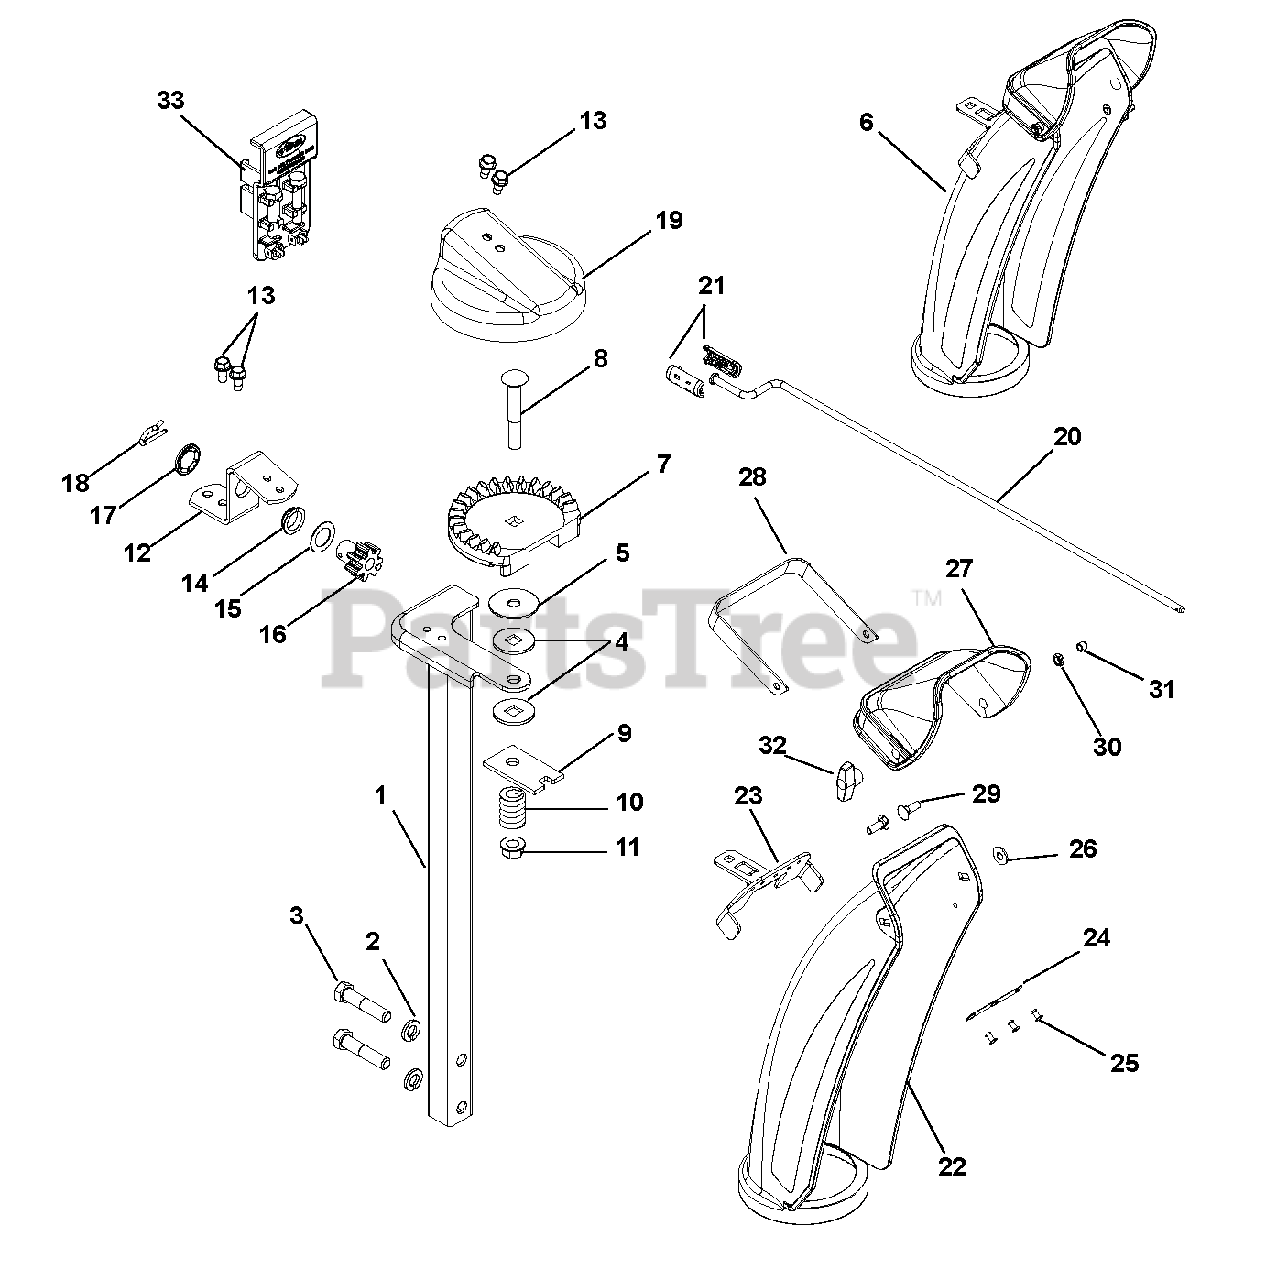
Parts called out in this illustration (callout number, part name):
1	CHUTE PEDESTAL, TALL COMPACT
2	@WSHR-LK .38X.094 REG YWZC
3	@BLT-HEX .38-16X1.75 GR5 YWZC
4	FRICTION WASHER
5	@WSHR-FL-STL .406X1.25X.10 ZC
6	CHUTE, MANUAL DISCHARGE W/CAP
7	CHUTE GEAR
8	@BLT-RDHDSQNK .38-16X2.50 G5YZ
9	PLATE, FRICTION
10	SG-COMP .187X.56X1.62
11	@NUT-LK-TOP-FLG .38-16 YWZC
12	BRACKET, PINION GEAR
13	SCR-TAP .25-20X.50 HWH TR YWZ
14	BUSHING, POLYLINER-.63 SNAPIN
15	WSHR-THRST .625 X 1.0 X .03
16	PINION GEAR W/BRACKET
17	PUSHNUT .625
18	PIN, SPRING CLIP
19	GEAR COVER
20	ROD, CHUTE CRANK - SINGLE SPD
21	KNOB, CHUTE CRANK - SNAP BLK
22	CHUTE, PLASTIC DISCHARGE LONG
23	CHUTE MOUNT BRACKET
24	PLATE,CHUTE MOUNT BACKING
25	RIVET, #66 STEEL POP PD BLACK
26	@WSHR-FL-STL.38X.875X.083 YWZC
27	DEFLECTOR CAP, PLASTIC
28	HANDLE, MANUAL CHUTE CAP
29	BLT,RNHDRECSHNK .31-18X1.00
30	@NUT-LK-CTR-JAM .31-18 YWZC
31	CAP, END .281X.313
32	KNOB, WING .31-18 UNC
33	HOLDER W SMALL SHEAR BOLT /NUT
